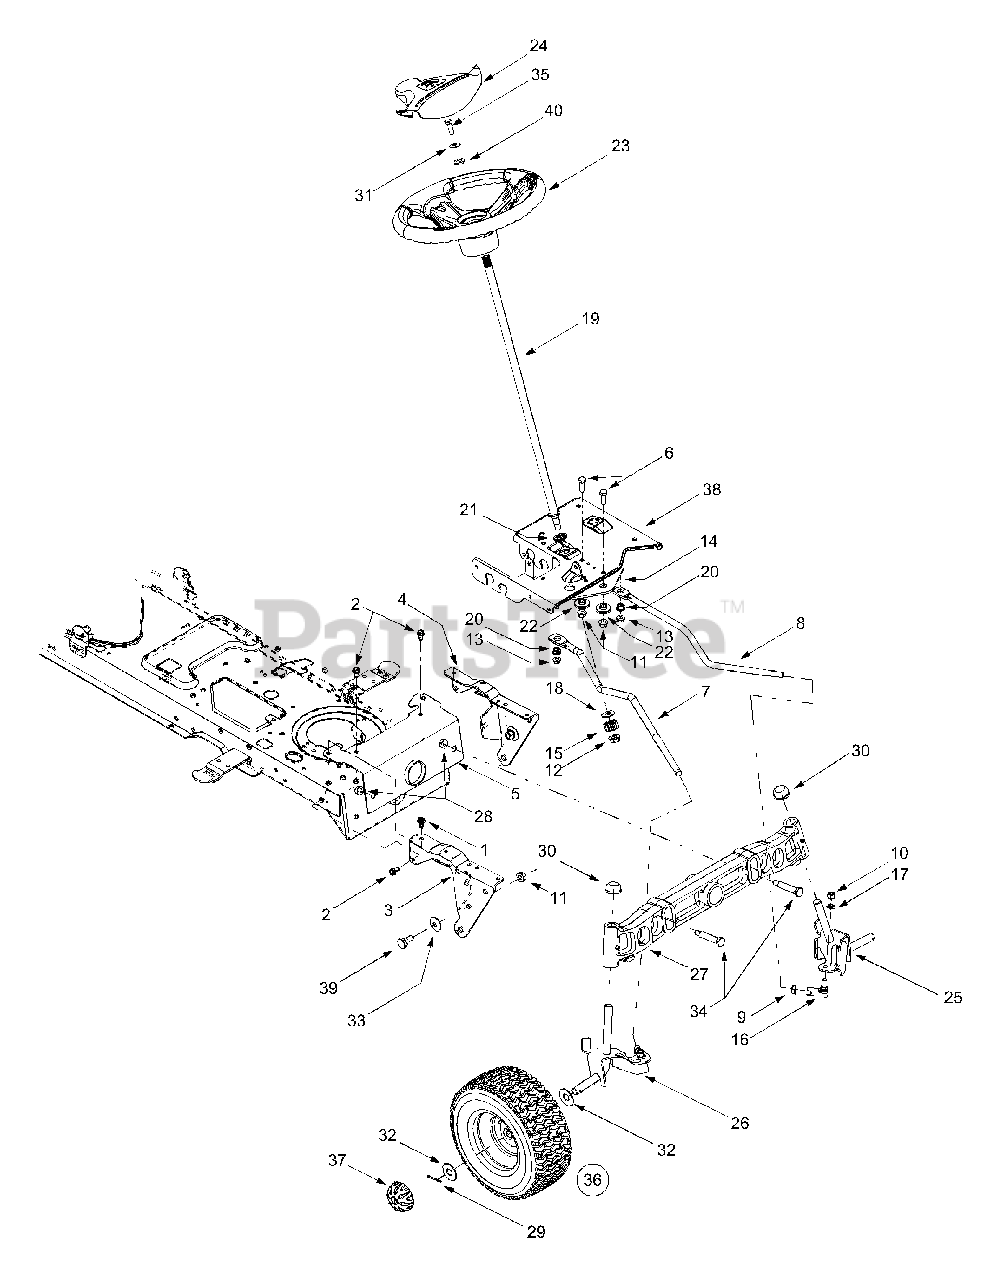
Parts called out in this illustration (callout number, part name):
1	Self-tapping Screw, 5/16-18 x .75
2	Self-tapping Screw, 16-18 x .625
6	Hex Cap Screw, 3/8-16 x 1 (Grade 5)
7	RH Drag Link
9	Jam Nut, 7/16-20 (Grade 2)
10	Hex Nut, 3/8-24 (Grade 2)
11	Flange Lock Nut, 3/8-16
12	Flange Lock Nut, 7/16-20
13	Flange Lock Nut, 5/16-18
14	Steering Gear, 11/90 Ratio
15	Steering Pinion Gear
16	Ball Joint, 7/16-20
17	Lock Washer, 3/8
18	Flat Washer, .51 x 1.12 x .06
19	Steering Shaft, .625 OD x 24.4
20	Plastic Bushing, .38 ID
21	Hex Flange Bearing, 5/8
22	Shoulder Spacer, .38 ID
23	Steering Wheel, Soft Grip, Three Spoke
24	Steering Wheel Cover
25	LH Axle Assembly, .625 Dia. (Model LT-1650)
25	LH Axle Assembly .625 / .750 Dia. Model LT-1850)
26	RH Axle Assembly, .625 Dia. (Model LT-1650)
26	RH Axle Assembly .625 / .750 Dia. Model LT-1850)
27	Cast Iron Pivot Bar w/ Fittings, .625 (Model LT-1650)
27	Cast Iron Pivot Bar w/ Fittings, .75 (Model LT-1850)
28	Flange Lock Nut, 3/8-16
30	Push Cap, .625 (Model LT-1650)
30	Push Cap, .750 (Model LT-1850)
31	Bell Washer, .34 x .872
32	Flat Washer, .635 x 1.589 x .06
33	Bell Washer, .39 x 1.13 x .062
34	Shoulder Screw, .5 x 2.2, 3/8-16
35	Hex Bolt, 5/16-18 X 1
37	Hub Cap
39	Shoulder Screw, 3/8-16
40	Flat Washer, .406 x .875 x .105
